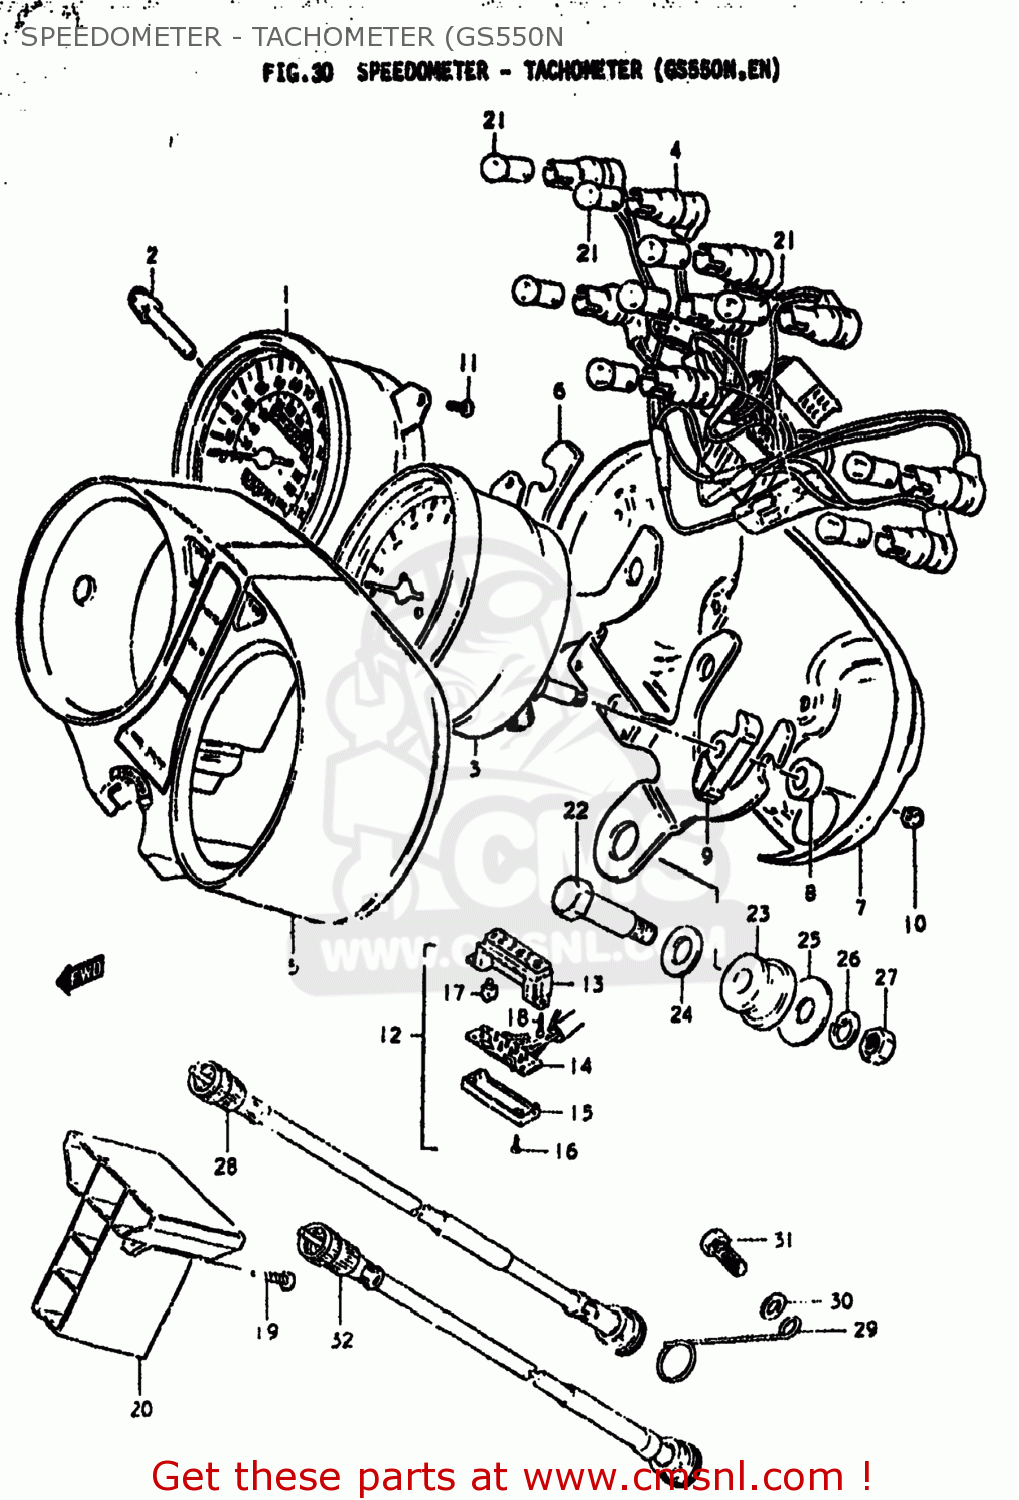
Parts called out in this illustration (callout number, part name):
1	SPEEDOMETER ASSEMBLY
2	KNOB
3	METER,TACHOMETER
4	SOCKET,METER
5	CASE
6	BRACKET,COMBINATION METER
7	COVER,UNDER
8	CUSHION,METER (A)
9	CUSHION,METER (B)
10	NUT
11	SCREW
12	INDICATOR ASSEMBLY,GEAR POSITION
13	CASE,GEAR INDICATOR
14	SOCKET,GEAR INDICATOR
15	COVER,LWR
16	SCREW,GEAR INDICATOR
17	BULB(14V1.12W)
18	SCREW
19	SCREW
20	CASE,PILOT BULB
21	BULB(12V3.4W,STANLEY,A72A)
22	BOLT(8X31)
23	CUSHION,METER
24	WASHER
25	WASHER (8.5X29X1.6)
26	LOCK WASHER
27	NUT
28	CABLE ASSEMBLY,SPEEDOMETER
29	GUIDE,SPEEDOMETER CABLE
30	WASHER 6MM
31	BOLT, UPPER
32	CABLE ASSEMBLY,TACHOMETER
